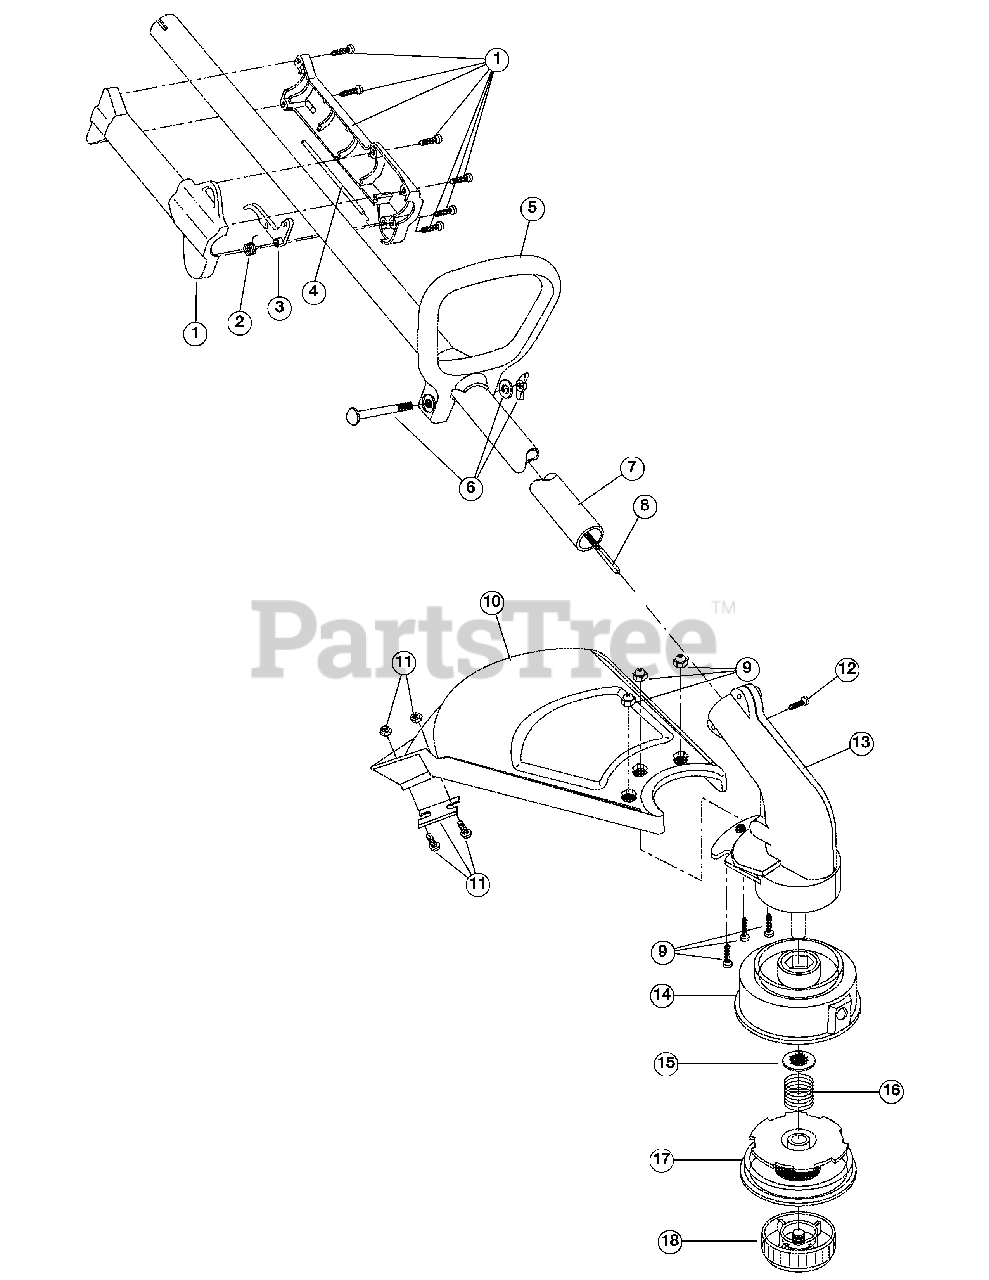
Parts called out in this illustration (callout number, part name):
1	Throttle Housing Assembly
2	Throttle Trigger Spring
3	Throttle Trigger
4	Throttle Cable
5	D-Handle
6	D-Handle Hardware
7	Drive Shaft Housing
8	Flexible Drive Shaft
9	Guard Mounting Screw Assembly
10	Guard Assembly
11	Blade Assembly
12	Anti-Rotation Screw
13	Gearbox Assembly
14	Outer Spool Assembly
15	Retainer
17	Inner Reel
18	Bump Head Knob Assembly
